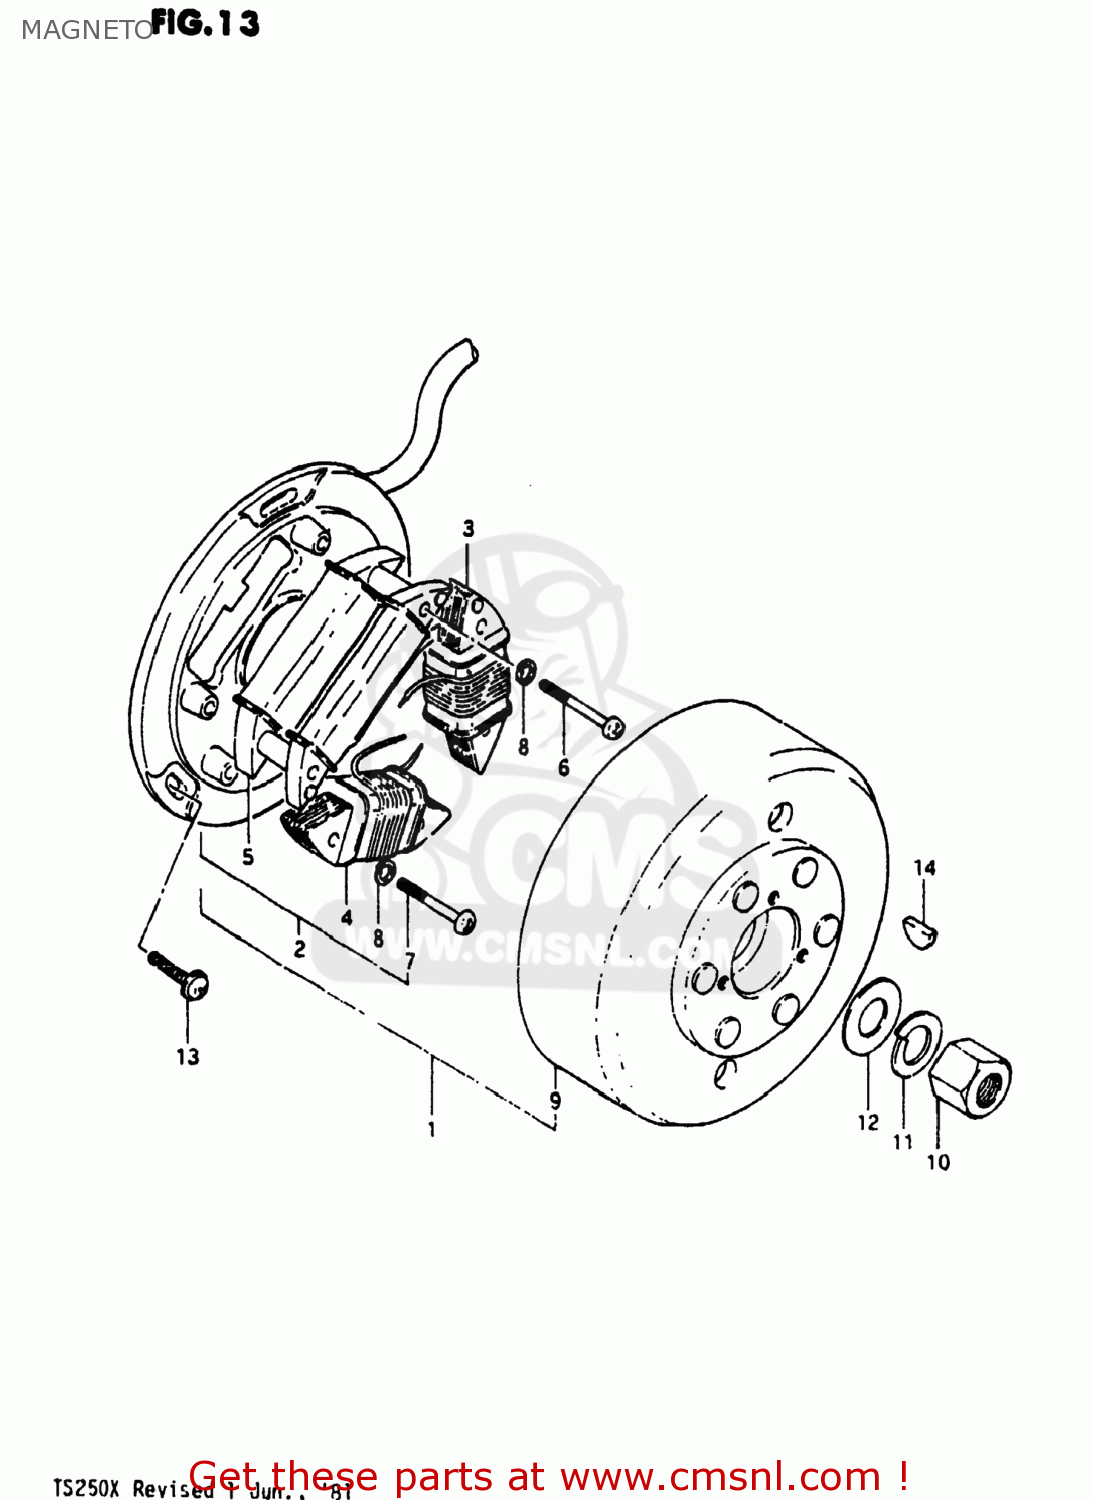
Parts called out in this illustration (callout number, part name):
1	MAGNETO ASSEMBLY
2	STATOR ASSEMBLY
3	COIL,LIGHTING
4	COIL,CHARGING
5	COIL,IGNITION
6	SCREW
7	SCREW 5X20
8	LOCK WASHER
9	ROTOR,FLYWHEEL
10	NUT
11	LOCK WASHER
12	WASHER(14X27X3)
13	SCREW(5X14)
14	KEY 4MM
